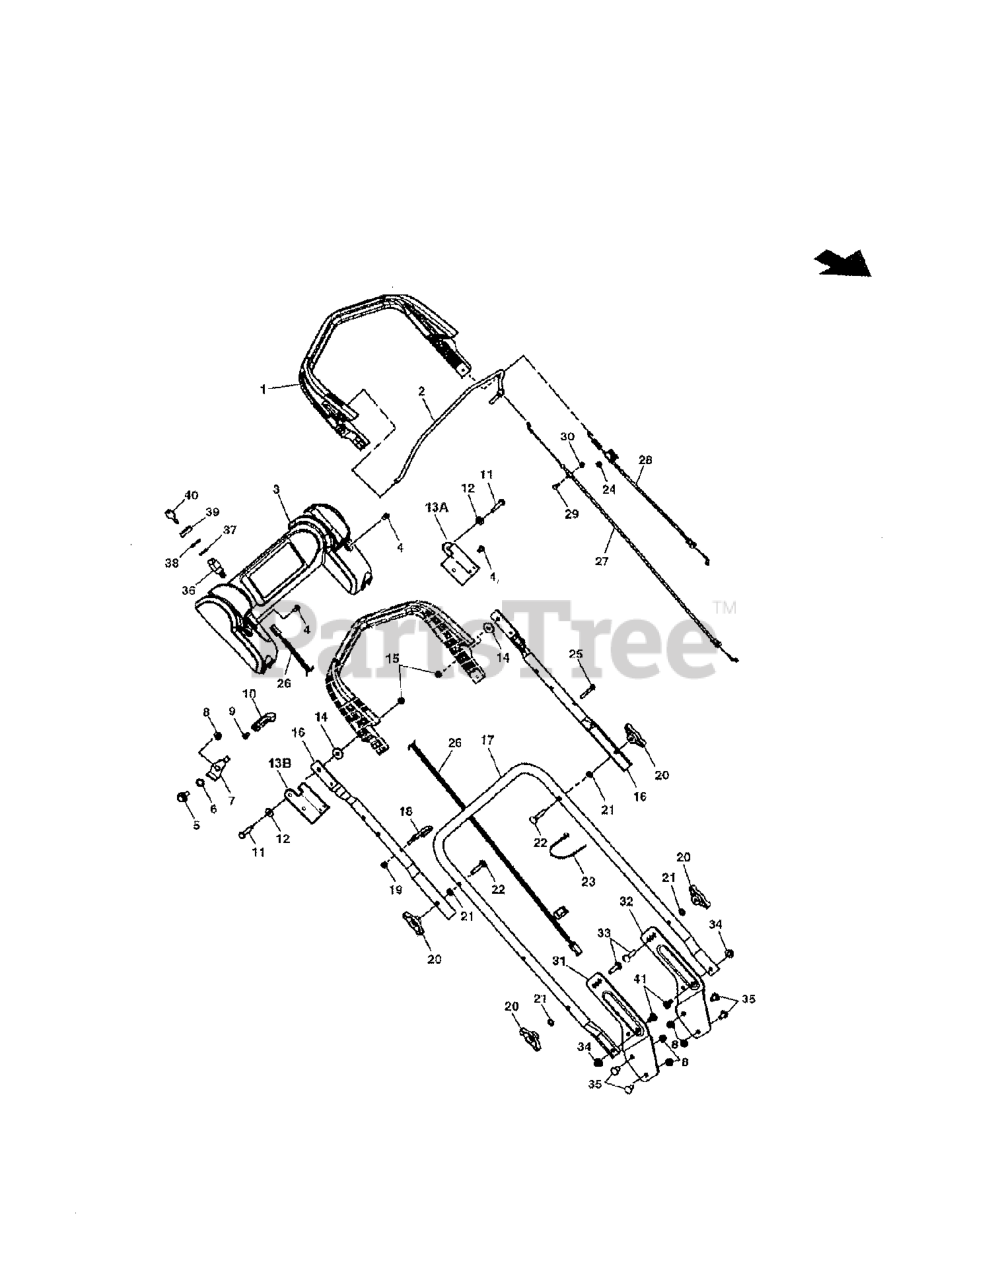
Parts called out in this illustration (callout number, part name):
1	HANDLE, PIVOTING - DEERE WALK
2	BAIL, PIVOTING HANDLE - 21" JD WBM
3	PANEL, UPPER HANDLE, DEERE
4	TORX ST, 1/4-20 X .550
5	IDLER PIVOT BOLT
6	WASHER, .531 X .781 3-WAVE
7	HANDLE, LOCK
8	FLN, 5/16-18 YZ
9	RIVET, PLASTIC SNAP
10	THROTTLE CONTROL LEVER
11	BOLT, SHOULDER, 5/16 X 2.500, YZ
12	SHIM WASHER, 5/16 I.D.
13A	BRACKET, LH, ROTATION LIMIT
13B	BRACKET, RH, ROTATION LIMIT
14	WASHER, FLAT, 1" OD X .387 ID
15	NUT, HEX FLANGE, 1/4-20, ESNA, YZ
16	HANDLE, UPPER, STRAIGHT, EASY LINE
17	HANDLE, LOWER 21" RD, JD
18	GUIDE, ROPE
19	HN, 1/4C NYL RNG
20	KNOB, HANDLE, 5 PRONG
21	ITLW 5/16
22	CHSNB, 5/16-18 X 2 GR2
23	WIRE TIE, 11 INCH STD BLK NYLON
24	HCLN, 1/4-20
25	HHCS,1/4CX1-3/4
26	WIRE HARNESS, DEERE - JS35
27	CABLE, CONTROL, ZONE (55.61" overall anchor to Z)
28	CABLE, DRIVE, 21" WBM, RD, DEERE (47.88" overall length)
29	RHSNB, 10-24X3/4, YZ
30	HLN, 10-24 UNC-2B W/NYLON INSERT
31	BRKT, LOWER HANDLE, RH, JD 21" WBM, RD
32	BRKT, LOWER HANDLE, LH, JD 21" WBM, RD
33	BOLT, RD HD SH SQ NK 5/16-18X1.500 G5 YZ
34	LHCLN, 5/16-18- BLACK
35	RHSSNB, 5/16-18 X 3/4 GR5 YZ
36	SWITCH, E/S (START/RUN)
37	SPACER, .65X.88X.10
38	HN, 5/8-32 (IGN SWITCH)
39	BEZEL
40	IGNITION KEY, PR
41	RHSSNB, 5/16-18 X 3/4 GR5 BZ
